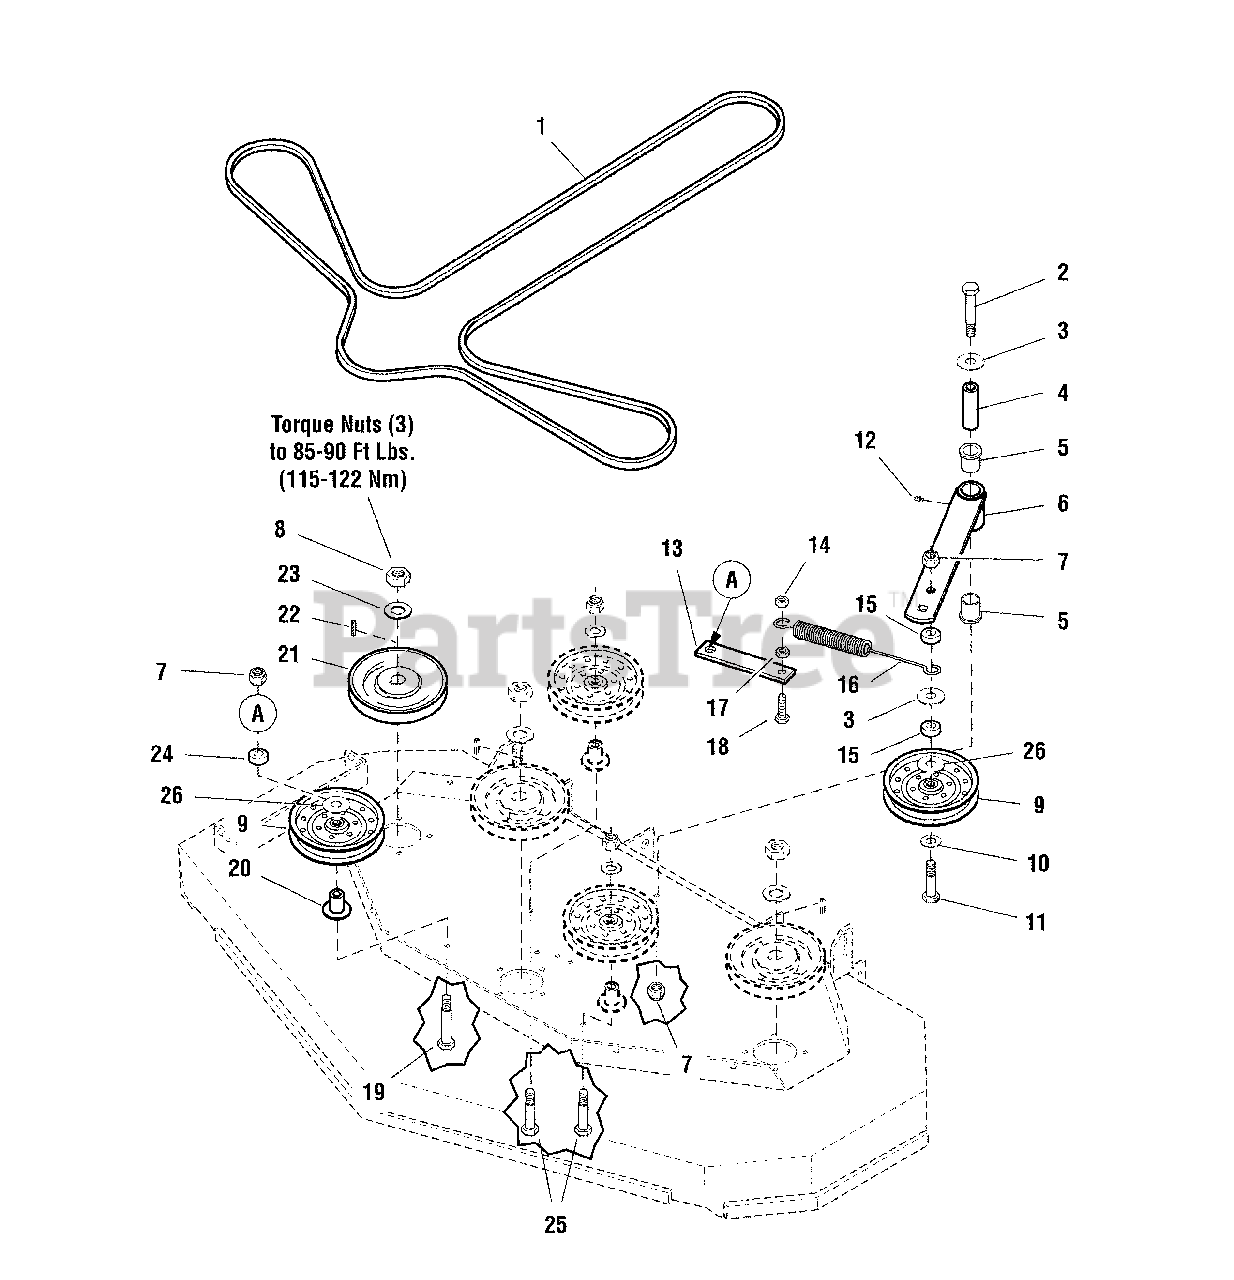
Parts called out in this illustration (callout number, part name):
1	BELT, 5V, 175.90EL, LG ARAMID, WRPD, RC
2	BOLT, 1/2-13 X 4-1/2 GD5
3	WASHER, 1/2 USS
4	SPACER, .52 X 1.00 X 3.50
5	BUSHING, FLANGE
6	ASSM, IDLER ARM - BLK - 5407039A (SV)
7	NUT, 1/2-13 HEX NYLOCK FLANGE
8	NUT, 3/4-16 HEX
9	*PULLEY, FLAT IDLER, 6-3/4"
10	WASHER, 1/2 GD9 YZ
11	BOLT, 1/2-13 X 2-3/4 GD5
12	GREASE FITTING, 1/4-28 STRAIGHT
13	MOUNT, IDLER SPRING - ORG
14	NUT, 3/8-16 HEX SIDE LOCK
15	SPACER, .52 X 1.00 X .38
16	SPRING, EXTENSION, SWIVEL END
17	NUT, 3/8-16 HEX SERRATED FLANGE
18	BOLT, 3/8-16 X 1-1/4 GD5
19	BOLT, 1/2-13 X 3-1/2 GD5
20	WELD, MOUNT, IDLER
21	PULLEY, 6.5 EOD X 25MM, SPLIT
22	KEY, 1/4 SQ. X 1-1/4
23	WASHER, 3/4 BELLEVILLE
24	SPACER, .52 X 1.00 X .44
25	BOLT, 1/2-13 X 3 GD5
26	SHIELD, PULLEY BEARING
